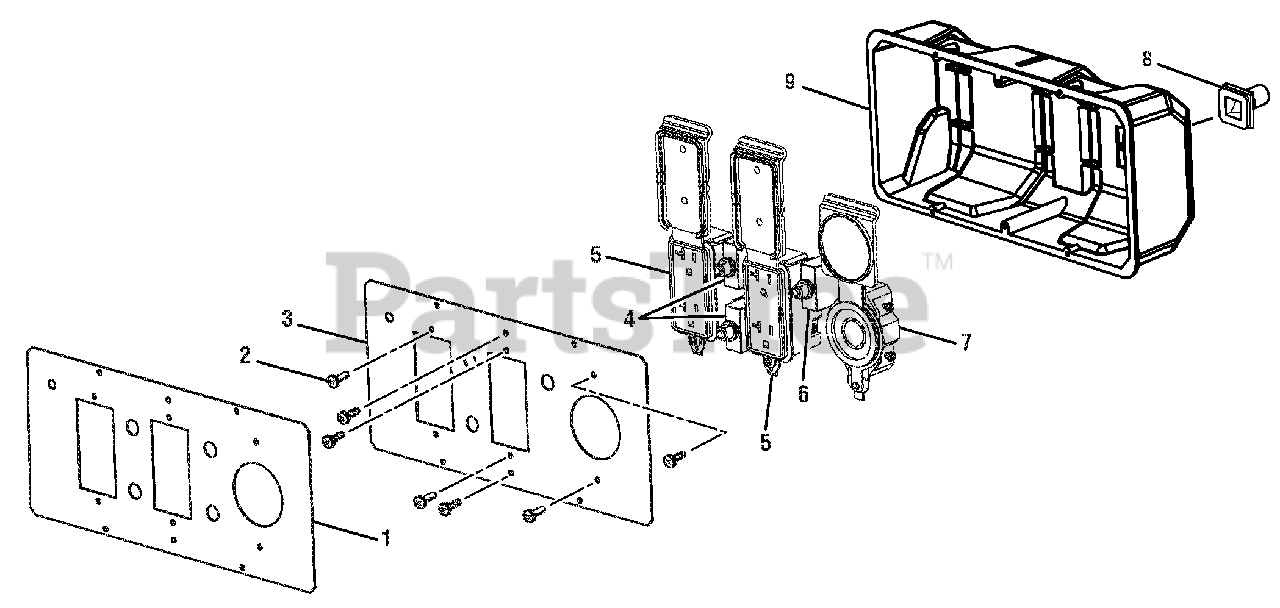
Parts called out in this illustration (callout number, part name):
1	LABEL (POWER OUTLET)
2	SCREW (6-20 X 3/8 IN.)
3	FRONT PANEL
4	CIRCUIT BREAKER (20 AMP
5	120 VOLT DUPLEX RECEPTACLE
6	CIRCUIT BREAKER (30 AMP)
7	TWST LCK RECEPT 120/240VLT 30A
8	RUBBER BOOT
9	CONTROL BOX (BACK PANEL)
